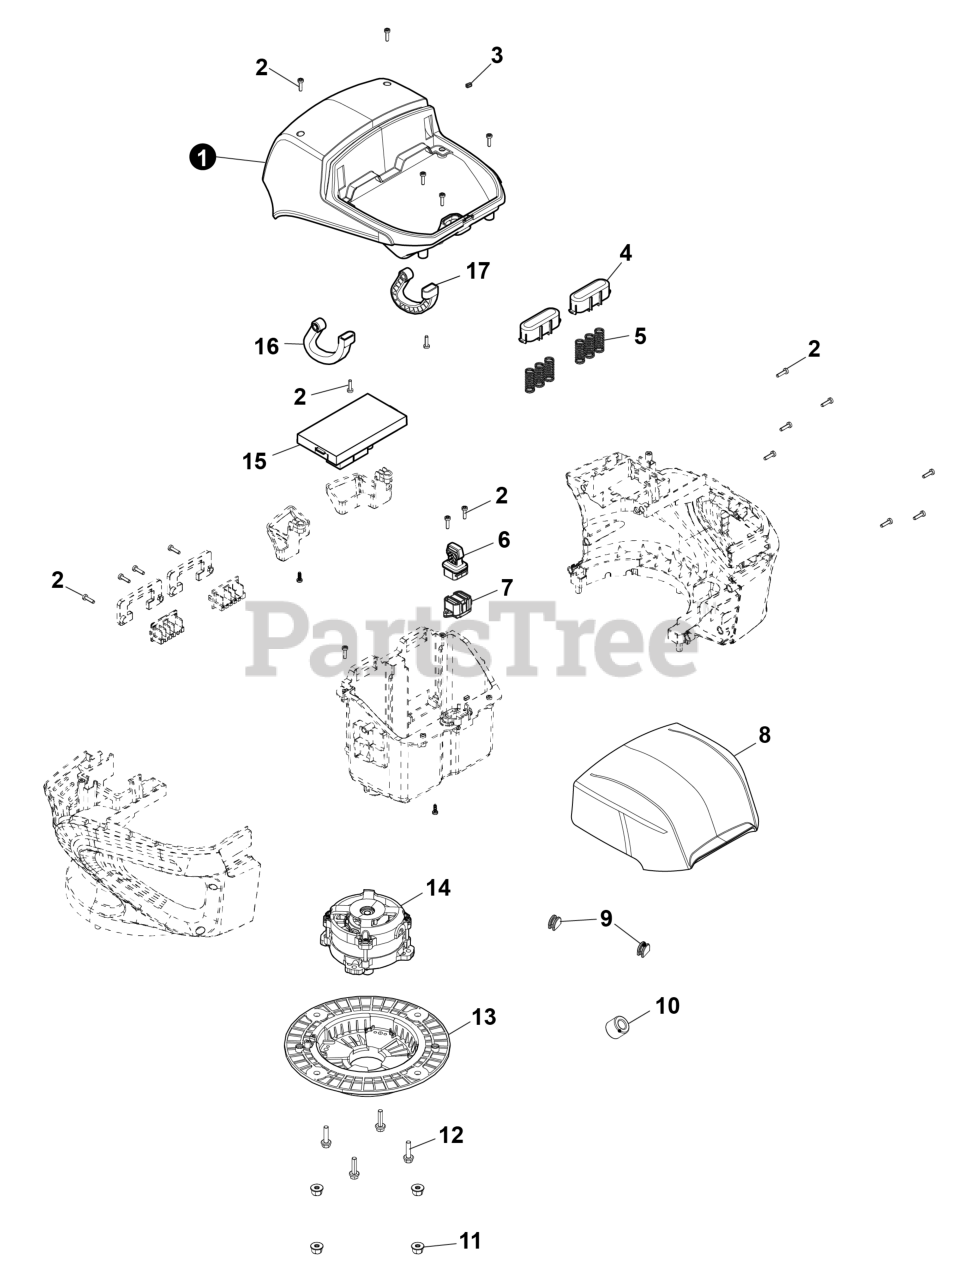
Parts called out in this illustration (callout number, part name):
1	COVER, UPPER
3	PLUG, RUBBER
4	COVER, BATTERY SPRING
7	SWITCH, KEY
8	COVER,BATTERY
9	PLUG,RUBBER
10	RING,MAGNETIC
13	COVER,MOTOR
